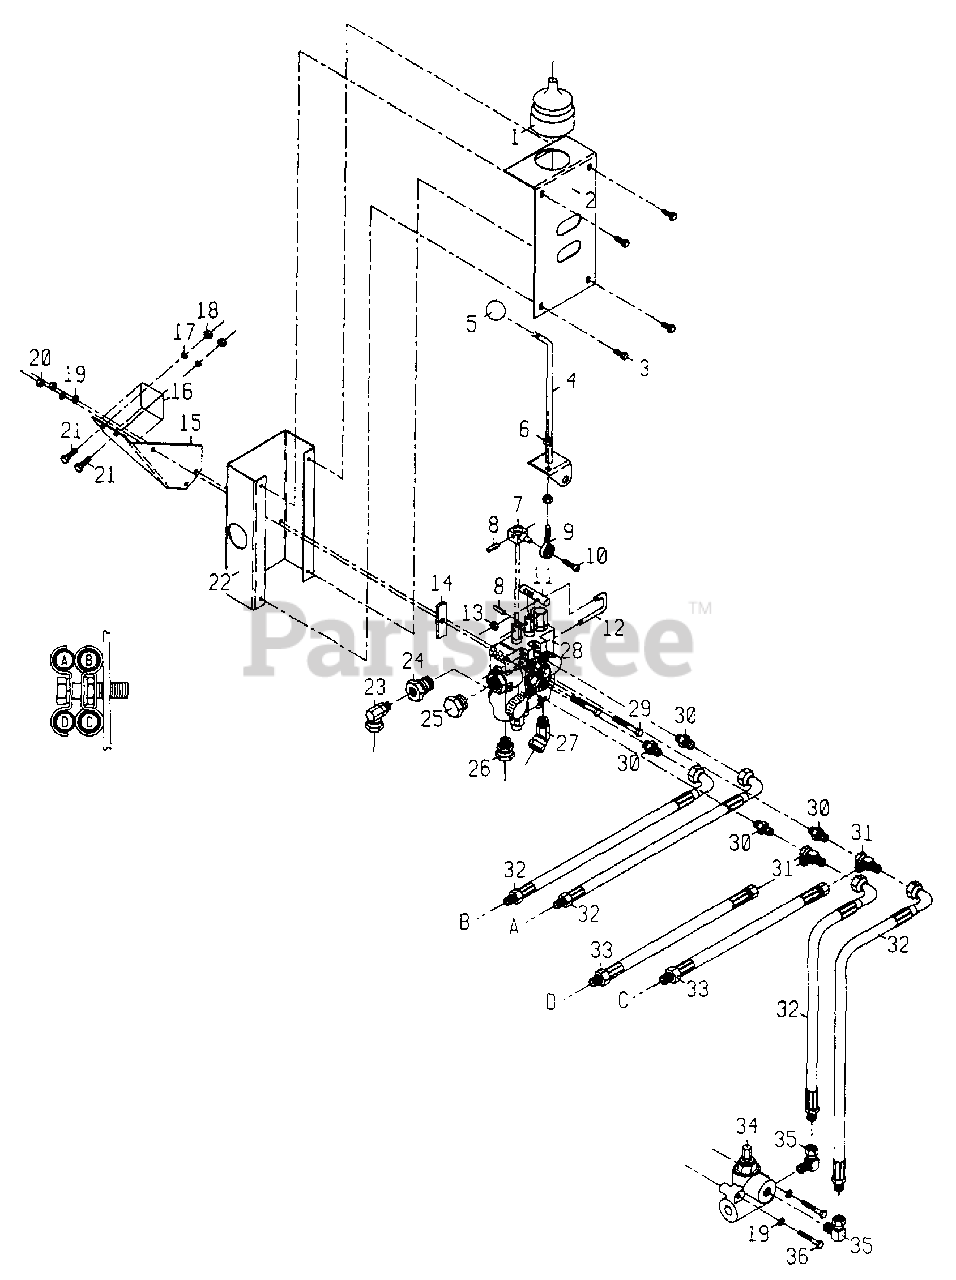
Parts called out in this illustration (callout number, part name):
1	Rubber Boot
2	End Cover
3	1/4 NC x 3/4 Self-tap screw
4	Handle
5	Calip Ball
6	5/16 NF Hex nut
7	Pivot block
8	1/4 x 7/8 Roll Pin
9	Rod End Ball Joint
10	1/4 NF x 1 Socket screw
11	Pin
13	1/4 NC Self-lock hex nut
15	Valve Mounting Bracket
16	Decal - Control Valve
17	3/8 Lockwasher
18	3/8 NC Hex nut
19	1/4 Lockwasher
20	1/4 NC Hex nut
21	3/8 NC x 1 Capscrew
22	Valve Cover
23	90° Elbow
24	Power Beyond Sleeve
25	Cap Plug
26	Straight Adapter
27	45° Adjustable Female Pipe Swivel
28	Valve
29	1/4 NC x 2-1/4 Capscrew
30	Straight adapter
32	Pressure hose - L18
33	Hydraulic hose - L18
34	Hydraulic relief valve
35	90° Swivel elbow
36	1/4 NC x 1-3/4 Capscrew
